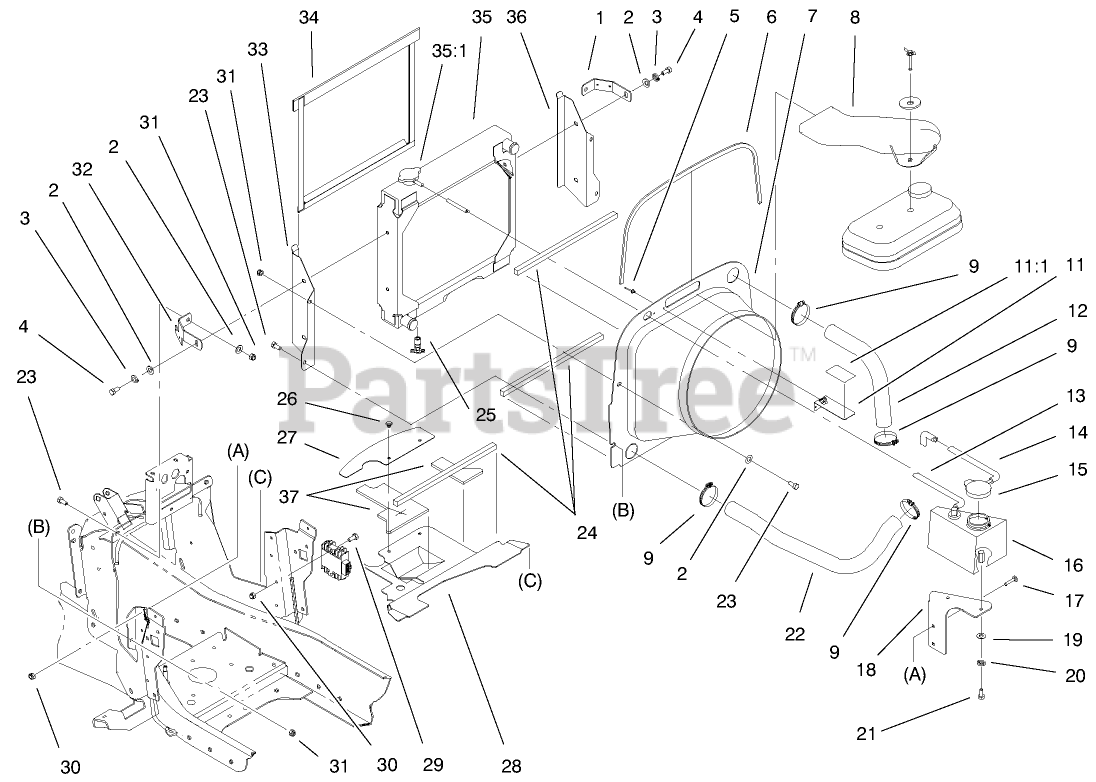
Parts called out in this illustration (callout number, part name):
2	WASHER-PLAIN
3	WASHER-LOCK
4	SCREW-HH
5	RIVET-POP
6	TRIM - LOC 31"
7	SHROUD - FAN
8	DUCT - AIR, KAWASAKI
9	CLAMP-HOSE
11	FAN/DECAL ASM
11:1	DECAL - WARNING
14	HOSE - OVERFLOW
16	BOTTLE - OVERFLOW
17	BOLT-CARR
19	WASHER-FLAT
20	WASHER-LOCK
21	SCREW-HH
22	HOSE - RAD. KAWASKI
23	SCREW-HH
24	FOAM - RADIATOR/SHROUD
26	RIVET - PLASTIC
27	BAFFLE - TOWER REAR
28	BAFFLE - TOWER
29	SCREW-HH
30	NUT-HEX
31	NUT-LOCK, NI
35	RADIATOR - GAS
35:1	CAP-RADIATOR
37	FOAM - BAFFLE
